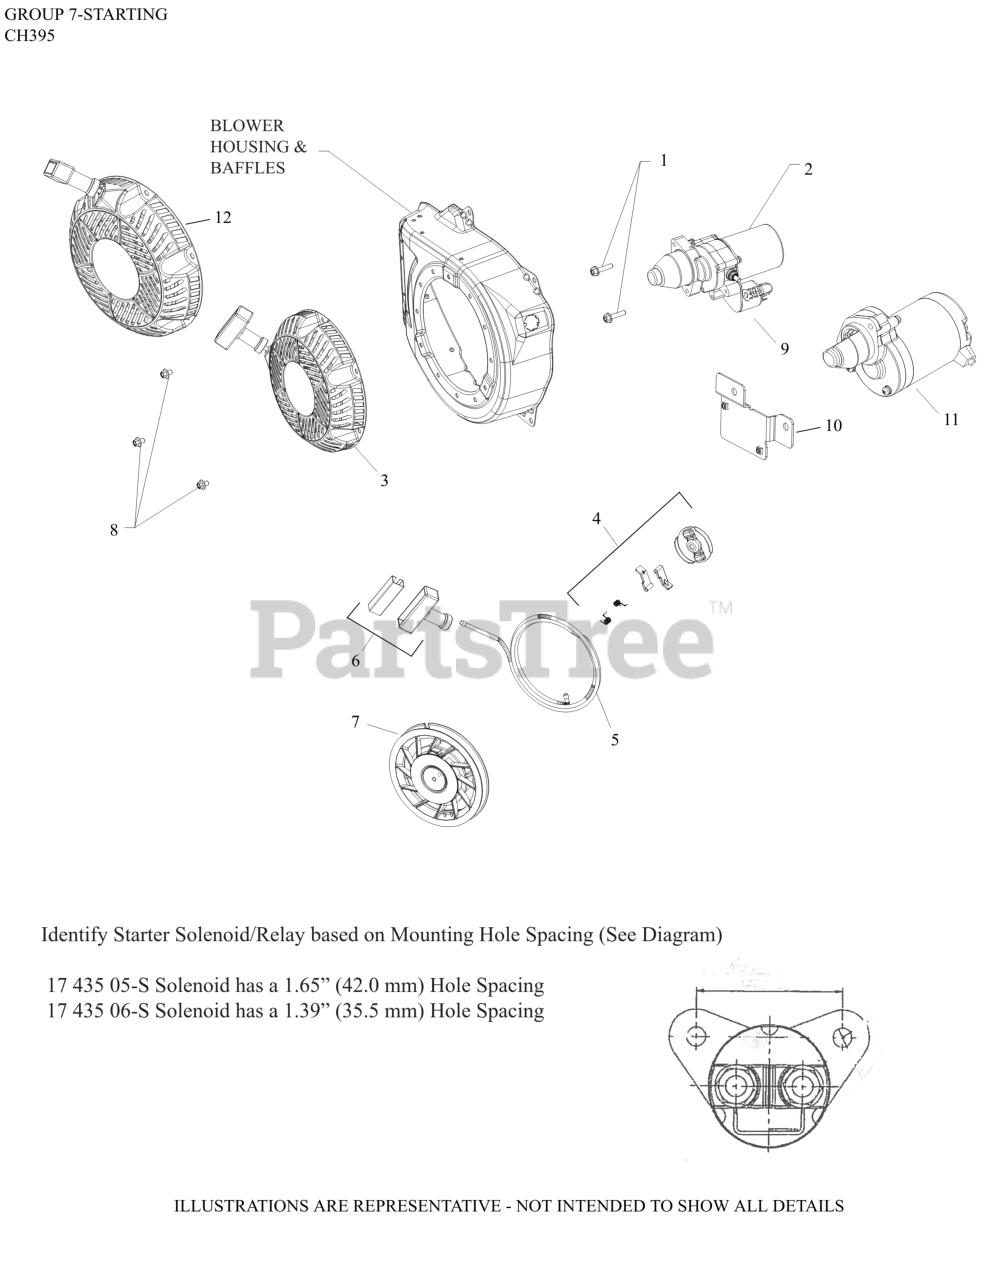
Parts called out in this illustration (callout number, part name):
3	RETRACTABLE STARTER ASSEMBLY
4	KIT, PAWL REPAIR
5	KIT, ROPE
6	KIT, HANDLE
7	PULLEY, RECOIL
8	SCREW, M6 X 8 HEX FLANGE HEAD
